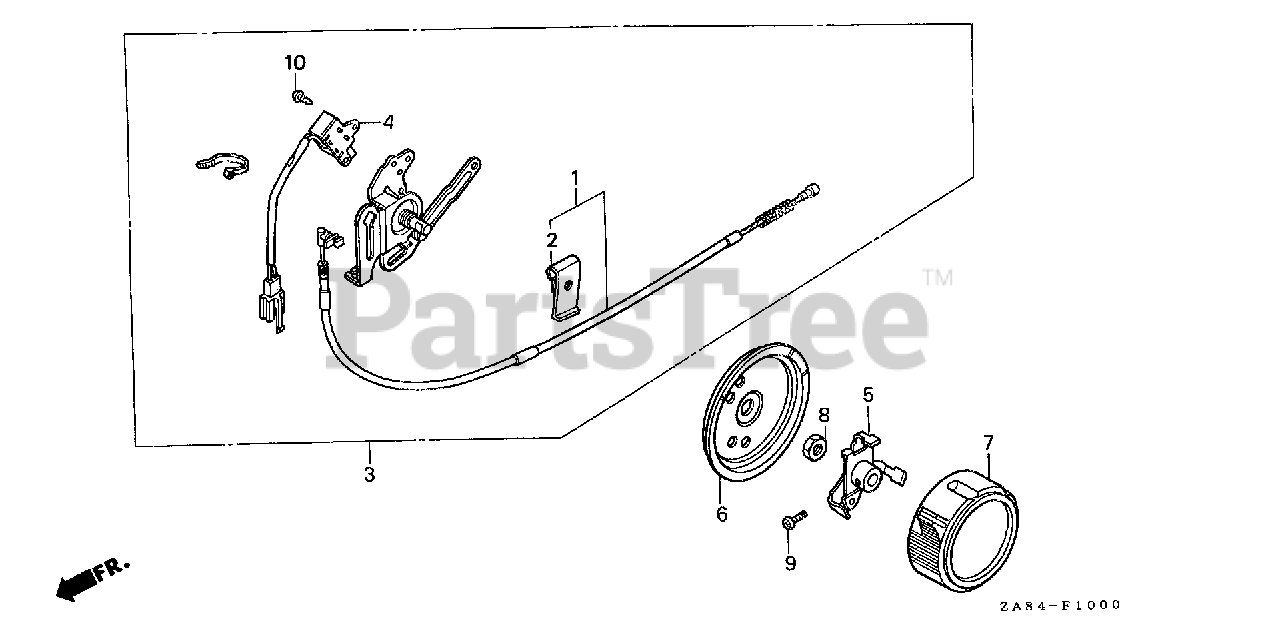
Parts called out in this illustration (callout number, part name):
1	CABLE, CHOKE
2	HOLDER, CHOKE CABLE
3	SWITCH ASSY., CONTROL (NOT AVAILABLE)
3	SWITCH ASSY., CONTROL
4	SWITCH ASSY., STOP
5	HOLDER, SWITCH KNOB
6	COVER, SWITCH CONTROL
7	KNOB ASSY., SWITCH
8	NUT, SPECIAL (10MM)
9	SCREW, PAN (3X8)
10	SCREW, TAPPING (3X8)
